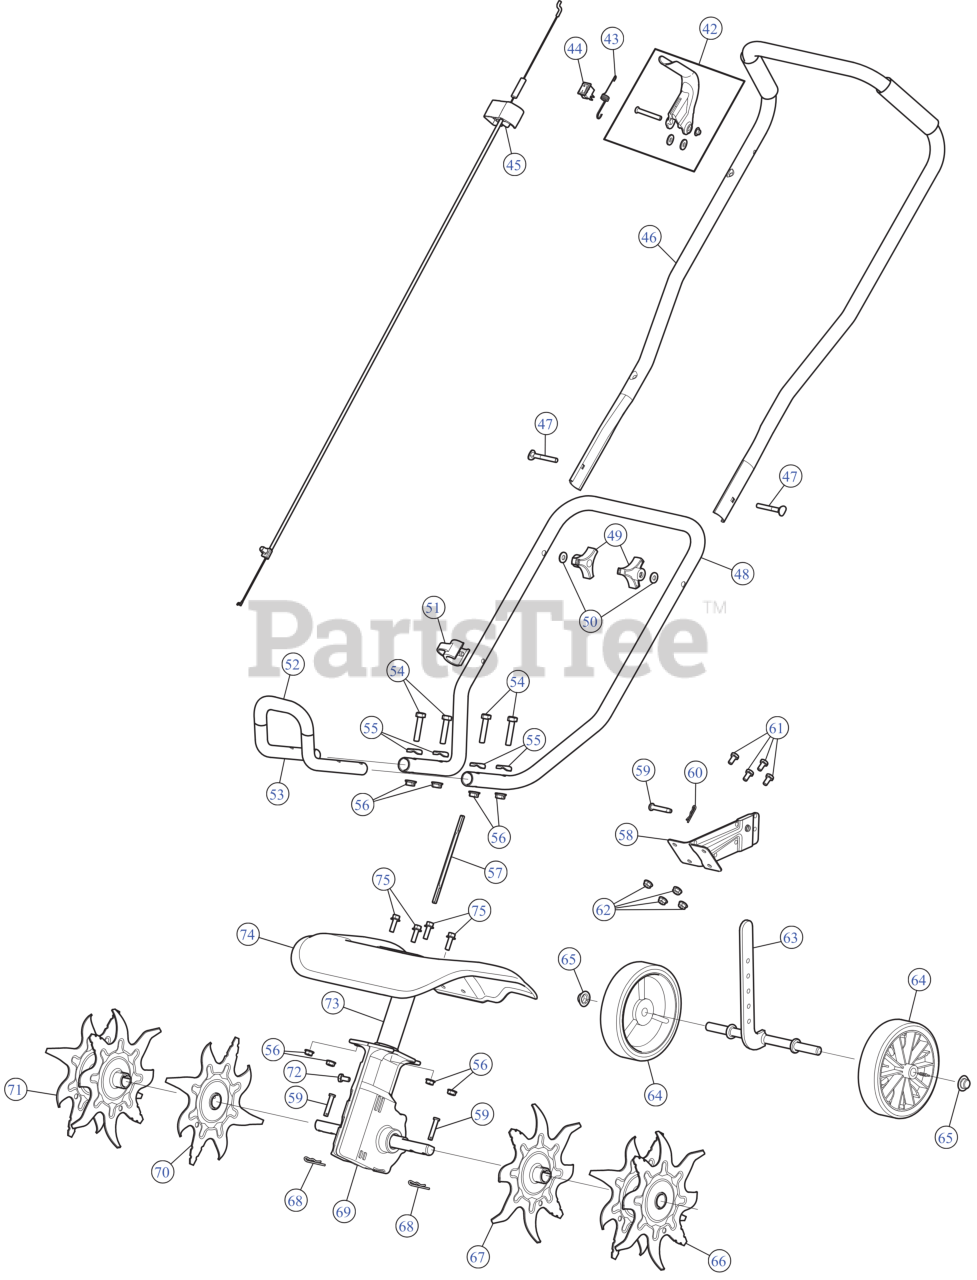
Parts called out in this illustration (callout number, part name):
42	THROTTLE LVR W/HDW
43	SPRING
44	SW, MOMENTARY ON/O
45	THROTTLE CABLE
46	HANDLE UPR CULT
47	BOLT, CARRIAGE CRV
48	LOWER HANDLE
49	KNOB, 3-PRONG ¼ "-
50	WASH, FLAT SPECIAL
51	CABLE GUIDE
52	FOAM GRIP - 9"
53	FRONT HANDLE
54	SCREW #
55	SADDLE WASHER
56	LOCK NUT 1/4
57	SHAFT-FLEX
58	TAILPIECE BRACKET ASSEMBLY
59	CLEVIS PIN
60	COTTER PIN .072 DIA. 1.13 LG
61	SCREW 1/4-20X.5 GR5
62	LOCK NUT 1/4
63	BRACKET ASSEMBLY
64	WHEEL 5-1.5 GRAY
65	PUSH CAP
66	TINE ASSEMBLY (LH)
67	TINE ASSEMBLY (LH)I (RH)O
68	COTTER PIN
69	GEARBOX ASSEMBLY CULT
70	TINE ASSEMBLY (LH)O (RH)I
71	TINE ASSEMBLY (RH)
72	SCREW 1/4-20 X.500
73	BOOM ASSEMBLY CULT
74	TINE SHIELD
75	HEX SCREW 1/4-20X.
